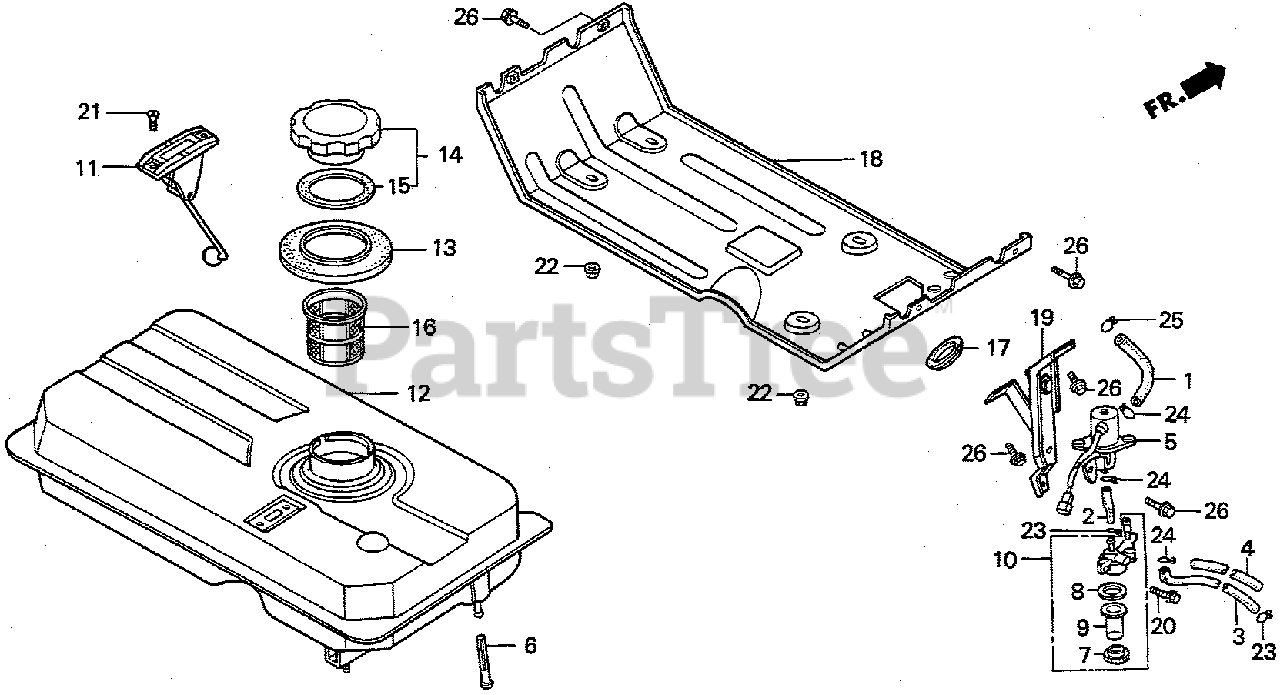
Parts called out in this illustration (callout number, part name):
1	TUBE, FUEL (TANK-VALVE)
2	TUBE, FUEL (VALVE-STRAINER)
3	TUBE, FUEL (STRAINER-CARBURETOR)
4	TUBE, FUEL SUPPORTER
5	VALVE ASSY., ELECTRIC FUEL
6	FILTER, FUEL
9	CUP, FUEL STRAINER
10	CUP ASSY., FUEL STRAINER
11	METER ASSY., FUEL
12	TANK, FUEL
13	SEAL, FUEL FILLER NECK
14	CAP, FUEL TANK
15	GASKET, FUEL FILLER CAP
16	FILTER, FUEL
17	GROMMET, WIRE
18	PLATE, FUEL TANK HANGER
19	BRACKET, STRAINER CUP SETTING
20	BOLT, FLANGE (5X12)
21	SCREW, FLAT (5X10)
22	NUT, FLANGE (6MM)
23	CLIP, TUBE (B8)
24	CLIP, TUBE (B10)
25	CLIP, TUBE (B12)
26	BOLT, FLANGE (6X12)
